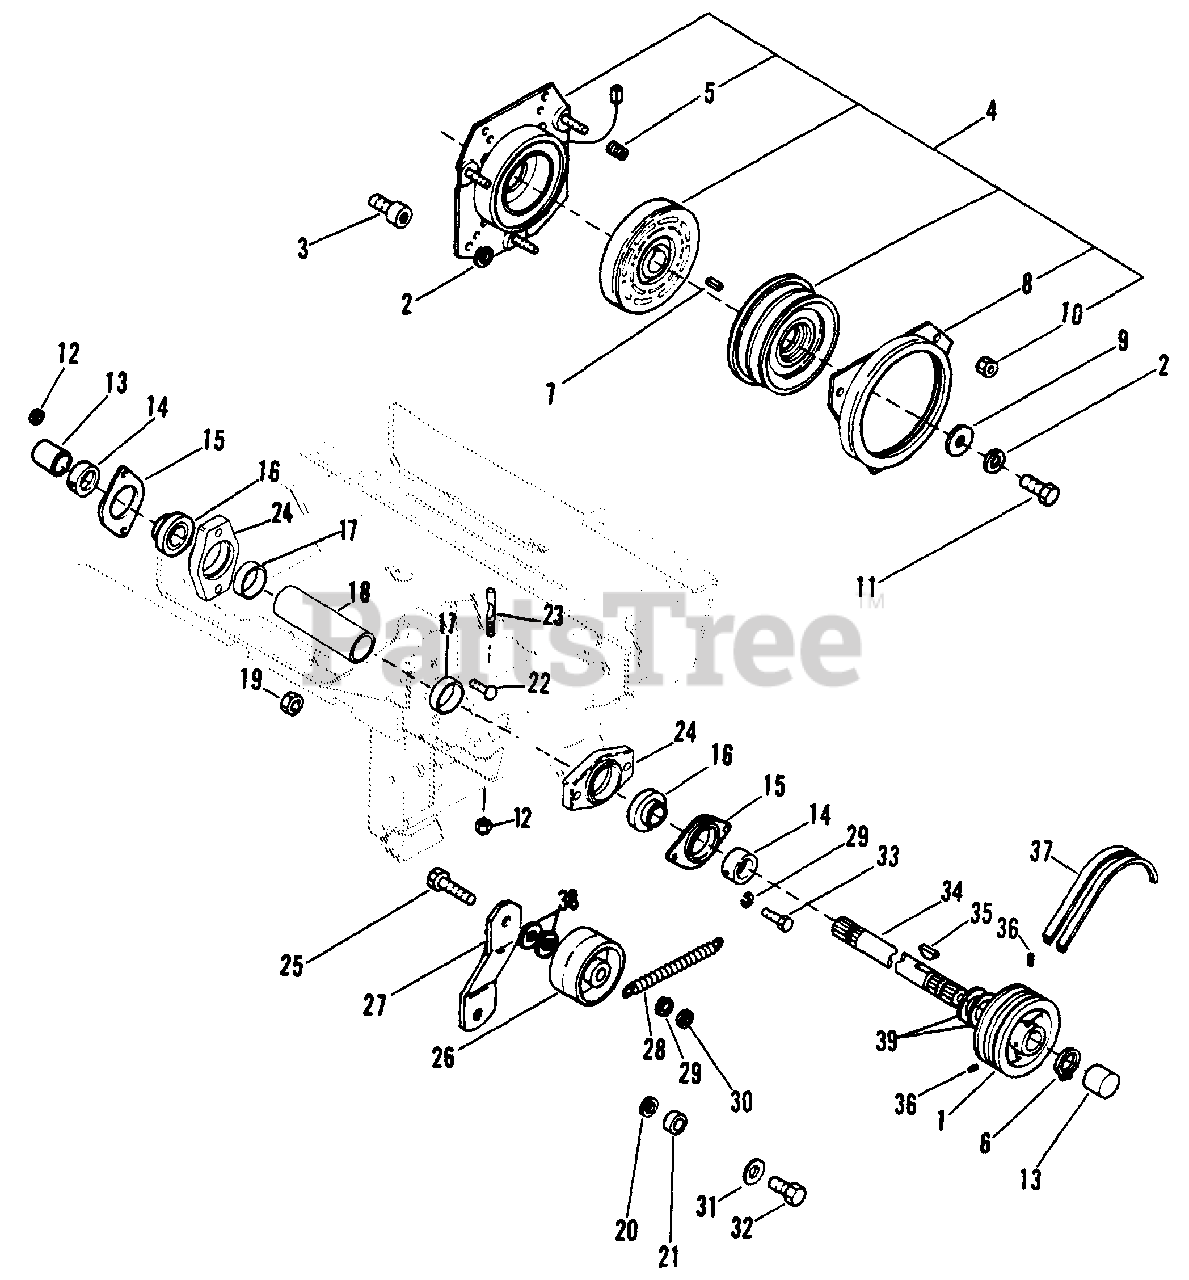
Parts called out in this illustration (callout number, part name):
1	Sheave
2	Washer, Lock 7/16 SP Heavy
3	Screw, Cap m10-1.5 x 16mm SH
4	Clutch Assembly 1.12 Bore
5	Spring, Comp.
6	Ring, Retaining
7	Key, Straight .25 x .625 x .25
8	Brake Drum
9	Washer, .510/.530 x 1.625 x .250
10	Nut, Lock 3/8-24
11	Bolt, Hex 7/16-20 x 1.50
12	Nut, Lock 3/8-16
13	Shaft Cover
14	Bearing Collar
15	Flange
16	Bearing, Ball 1" I.D. x 2-3/64 O.D.
17	Bushing
18	PTO Tube
19	Nut, Lock 1/2-13
20	Shim Spacer
21	Spacer
22	Bolt, 3/8-16 x 1.50 Rd Hd Sq Nk
23	Lock Stud
24	Bearing Flange
25	Bolt, Hex 3/8-16 x 2.00
26	Idler, .375 x 3.25
27	Idler Arm
28	Spring, Extension 6" Free Length
29	Washer, Lock 3/8 Reg.
30	Nut, Hex 3/8-16
31	Washer, .513/.523 x 2.000 x .105
32	Bolt, Hex 1/2-13 x 1.25
33	Bolt, Hex 3/8-16 x 1.50
34	Front PTO Shaft
35	Key, Feather .25 x 1.25 x .25
36	Setscrew, 5/16-18 x .38 SKHCUPNL
37	V-Belt(2) 4L-RMA
38	Washer, Flat .406 x .812 x .065
39	Washer, Flat 1.00 x 1.50 x .06
